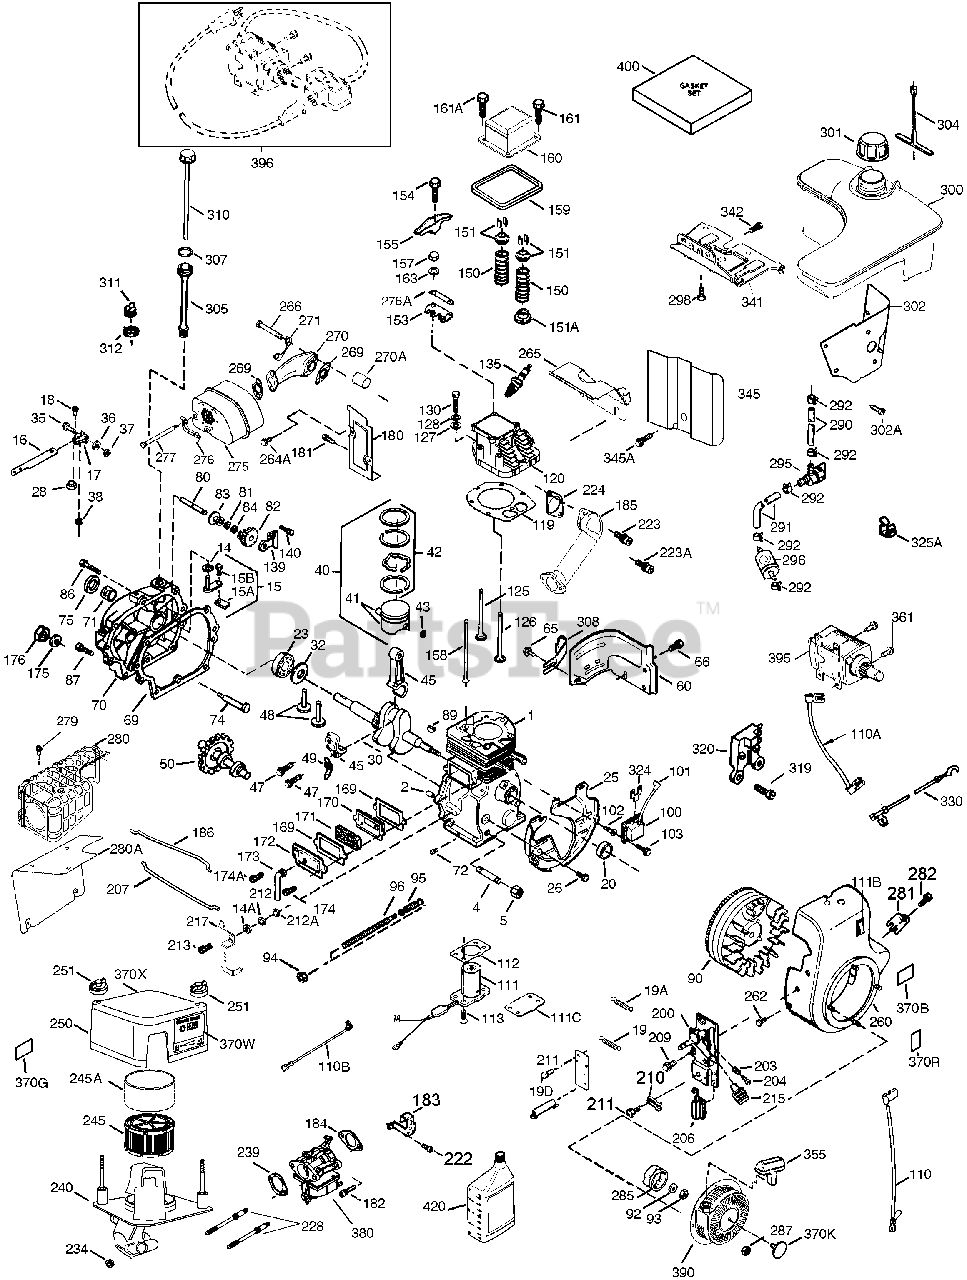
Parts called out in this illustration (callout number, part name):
1	"Cylinder (Incl. 2, 20, 72 & 72A) (3-1 /8" Bore)
2	Dowel Pin
14	Flat Washer
15	Governor Rod Ass'y (Incl. 15A & 15B)
15A	Governor Yoke
15B	Screw, 6-40 x 5/16"
16	Governor Lever Ass'y. (Incl. 212A)
17	Governor Lever Clamp
18	Screw, T-15, 8-32 x 3/8"
19A	Extension Spring
20	Oil Seal
23	Ball Bearing
25	Blower Housing Baffle (Incl. 325)
26	Screw, 1/4-20 x 19/32"
28	Nut & Lock Washer, 8-32
30	Crankshaft
35	Screw, 10-32 x 3/4"
36	Lock Washer #8
37	Lock Nut, 10-32
38	Retaining Ring
40	Piston, Pin & Ring Set (Std.)
40	Piston, Pin & Ring Set (.010" OS)
41	Piston & Pin Ass'y (Std.) (Incl. 43)
41	Piston & Pin Ass'y (.010" OS) Incl. 4 3
42	Ring Set (Std.)
42	Ring Set (.010" OS)
43	Piston Pin Retaining Ring
45	Connecting Rod Ass'y (Incl. 47 & 49)
47	Connecting Rod Bolt
48	Valve Lifter
49	Oil Dipper
50	Camshaft (MCR)
60	Blower Housing Extension
62	Screw, 8-32 x 3/8"
65	Screw, 10-24 x 9/16"
69	* Cylinder Cover Gasket
70	Cylinder Cover Incl. 74,75,80-84,175& 176
72	Oil Drain Plug (Sq. hd., 1/4-18)
74	Bearing Retainer
75	Oil Seal
80	Governor Shaft
82	Governor Gear Ass'y. (Incl. 81)
83	Governor Spool
84	Retaining Ring
86	Screw, 1/4-20 x 1-3/16"
87	Screw, 1/4-20 x 1-11/16"
89	Flywheel Key
90	Flywheel (W/Ring Gear)
92	Lock Washer
93	Flywheel Nut
100	Solid State Ignition (Incl. 101)
101	Spark Plug Cover
102	Solid State Mounting Stud
103	Screw, T-15, 10-24 x 15/16"
110A	Ground Wire - Black, 13.25''
110A	Ground Wire
110B	Ground Wire
111B	Rocker On/Off Switch
119	* Cylinder Head Gasket
120	Cylinder Head (Incl. 151A & 270A)
124	Screw, 1/4-20 x 5/8"
125	Exhaust Valve (Std.)
125	Exhaust Valve (1/32" OS)
126	Intake Valve (Std.)
128	Belleville Washer
130	Screw, 5/16-18 x 2-1/2"
135	Resistor Spark Plug (RN4C) also avail able in Packaged Part #740069
139	Governor Gear Bracket
140	Screw, 10-24 x 1/2"
150	Valve Spring
151	Valve Spring Keeper
151A	Intake Valve Seal
153	Push Rod Guide
154	Rocker Arm Stud
155	Rocker Arm
157	Jam Nut
158	Push Rod
159	* Rocker Arm Cover Gasket
160	Rocker Arm Cover
161	Screw, T-30, 1/4-20 x 1/2"
163	Lock Washer
169	* Valve Cover Gasket
170	Breather Body
171	Breather Element
172	Valve Cover
173	Breather Tube
174	Screw, 10-24 x 1/2"
175	Lock Washer
176	Lock Nut, 10-24
178	Nut & Lock Washer 1/4-28
180	Blower Housing Extension
182	Carburetor Mounting Stud
184	* Carburetor To Intake Pipe Gasket
185	Intake Pipe (Incl. 223 & 223A)
186	Governor Link
200	Remote Control Bracket (RV) (Incl. 20 3 & 204)
207	Throttle Link
210	Conduit Clip
211	Screw, 10-32 x 3/8"
212	Bushing
212A	Bushing
213	Screw, 10-24 x 29/32"
217	Bellcrank Lever
223	Screw, T-30, 5/16-18 x 1-3/32"
223	Screw, T-30, 5/16-18 x 1-7/16"
224	* Intake Pipe Gasket
228	Air Cleaner Stud
234	Air Cleaner Nut, 1/4-20
239	* Air Cleaner Gasket
240	Air Filter Body
245	Air Filter Also available in 740111 m erchandiser package.
245A	Air Filter (Poly)
250	Air Filter Cover
251	Wing Nut, 1/4-20
254A	Rocker Arm Stud/Bearing Kit (incl. re f. 155, 156, & 157)
260	Blower Housing
262	Screw, 5/16-18 x 9/16"
265	Cylinder Head Cover
266	Screw, 5/16-18 x 1-9/32"
269	* Exhaust Gasket
270	Exhaust Manifold
270A	Exhaust Port Liner
271	Locking Plate (Manifold)
275	Muffler
276	Locking Plate
276A	Locking Plate
277A	Screw, 5/16-18 x 4-1/2"
280	Heat Shield
281	Starter Bubble Cover
285	Starter Cup
291	Fuel Line
292	Fuel Line Clamp
298	Screw, 1/4-15 x 3/4"
300	Fuel Tank (Incl. 292 & 301)
301	Fuel Cap
302	Fuel Tank Extension
305	Oil Fill Tube
307	"O" Ring
308	Fill Tube Clip
309	Screw, 10-32 x 5/16"
310	Dipstick
325A	Wire Clip
338	Screw, 10-32 x 1/2"
341	Fuel Tank Bracket
345	Heat Baffle
345A	Screw, 5/16-18 x 7/8"
355	Starter Handle (Mitten Grip) also ava ilable in Packaged Part #740053B
370	Decal - Tecumseh Logo for Top of Reco il Starter
370	Decal - Climate Guard This side out f or use ABOVE 32 Degrees F.
370	Decal - Climate Guard This side out f or use BELOW 32 Degrees F.
380	Carburetor (Incl. 184)
390	Rewind Starter Note: This engine cou ld have been built with 590704 starte r.
400	Gasket Set (Incl. items marked *) not es)
420	SAE 30 4-Cycle Engine Oil (Quart)
